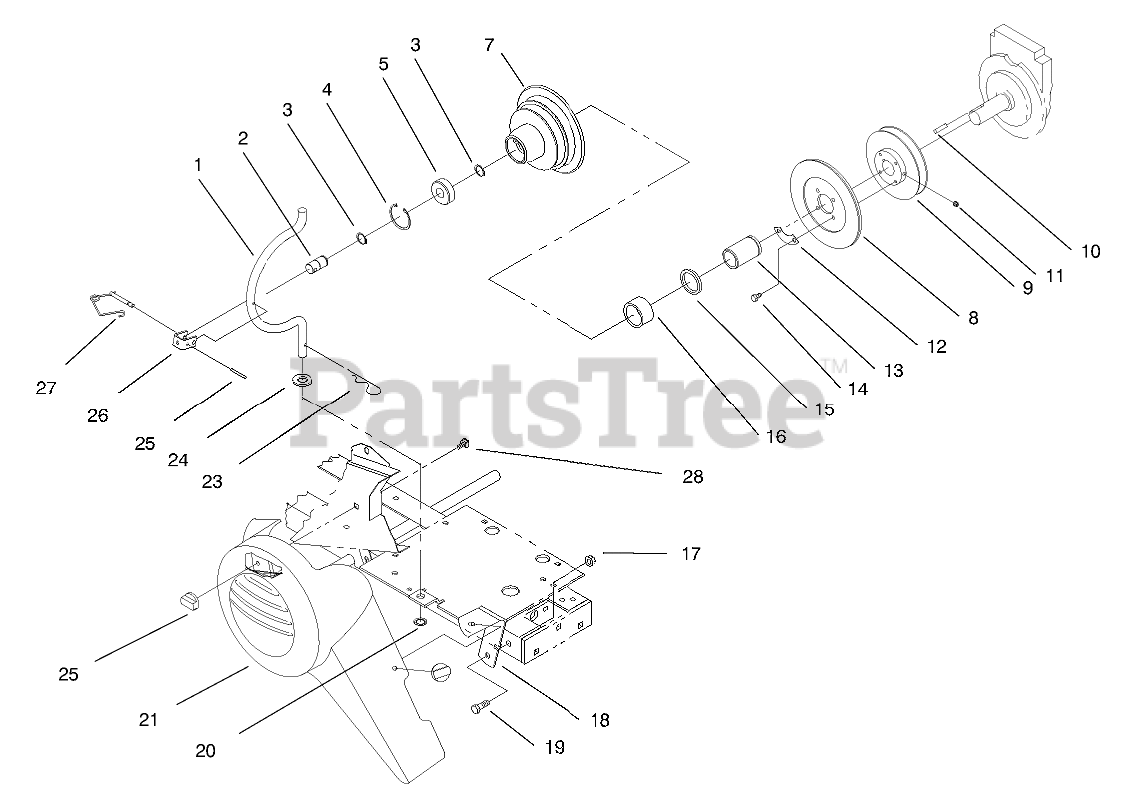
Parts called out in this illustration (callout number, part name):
1	ROD-HOUSING
2	SHAFT-PTO
3	Ring-Snap
4	RING-RETAINING
5	BEARING-BALL
7	Housing-Clutch
8	ASS'Y-CLUTCH PLATE
9	PULLEY
11	SCREW-SET, HSH
12	RETAINER
13	RACE-BEARING
14	SCREW-HEX HD CAP
15	SEAL-OIL
16	Seal
17	NUT-FLANGE
18	Bracket
19	SCREW-HH
20	RING-REINFORCED CIRC
21	GUARD - BELT
22	NUT - WING
23	PIN-COTTER, HAIR
24	WASHER-FLAT
26	CLEVIS
27	LOCKING PIN ASM
28	Retainer-Bolt
